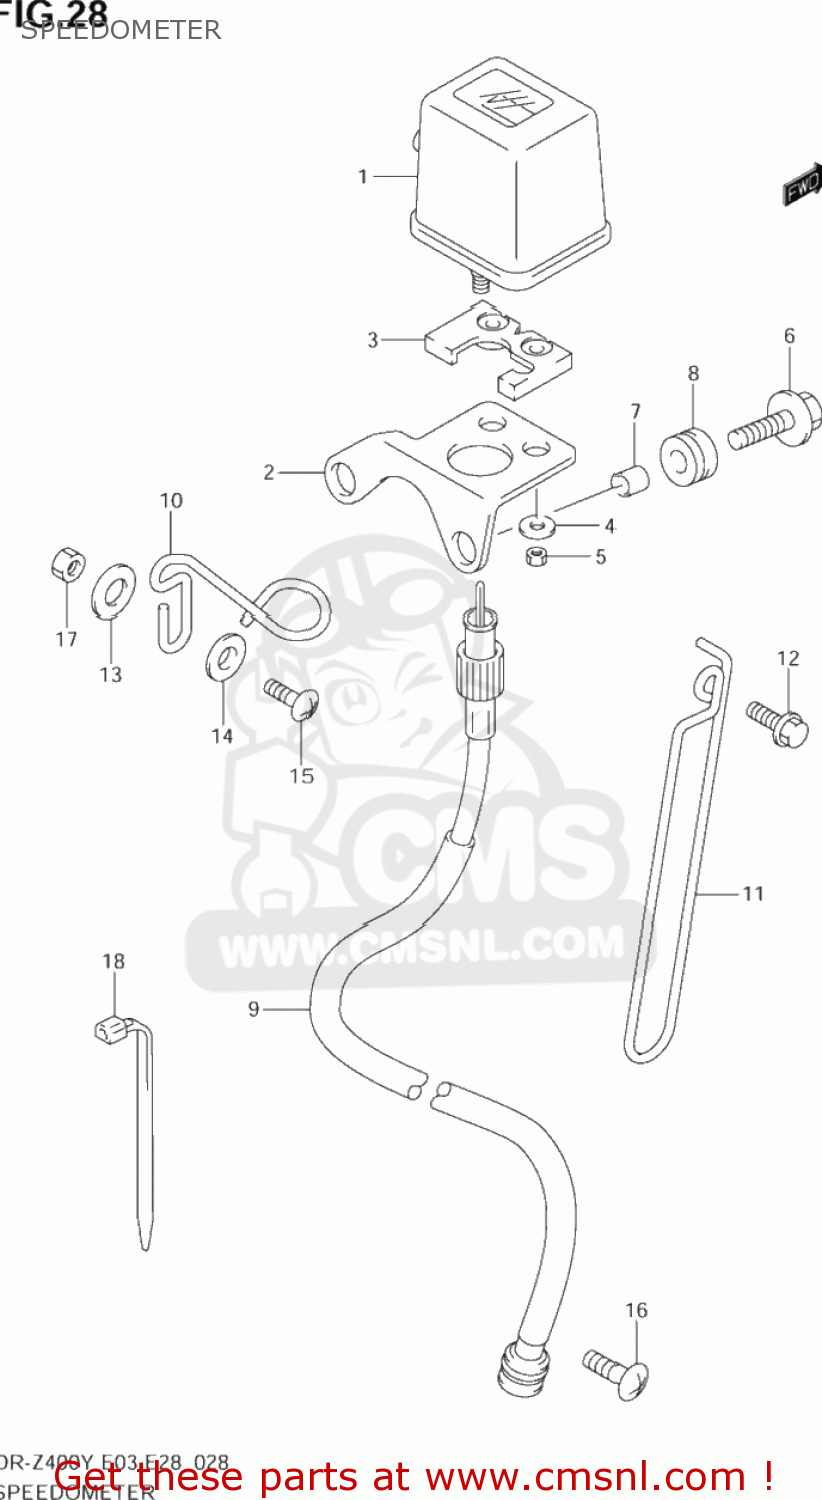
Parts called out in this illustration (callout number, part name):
1	TRIP METER
2	BRACKET
3	CUSHION
4	WASHER (4.3X13X0.80)
5	NUT
6	BOLT(6X25)
7	SPACER(6.1X8X9.5)
8	CUSHION
9	CABLE ASSY,SPEEDOMETER
10	GUIDE,SPEEDOMETER CABLE
11	GUIDE,METER CABLE NO.2
12	BOLT(6X20)
13	WASHER(6.5X18X1.6)
14	WASHER
15	SCREW
16	SCREW
17	NUT 6MM
18	CLAMP(L:235)
